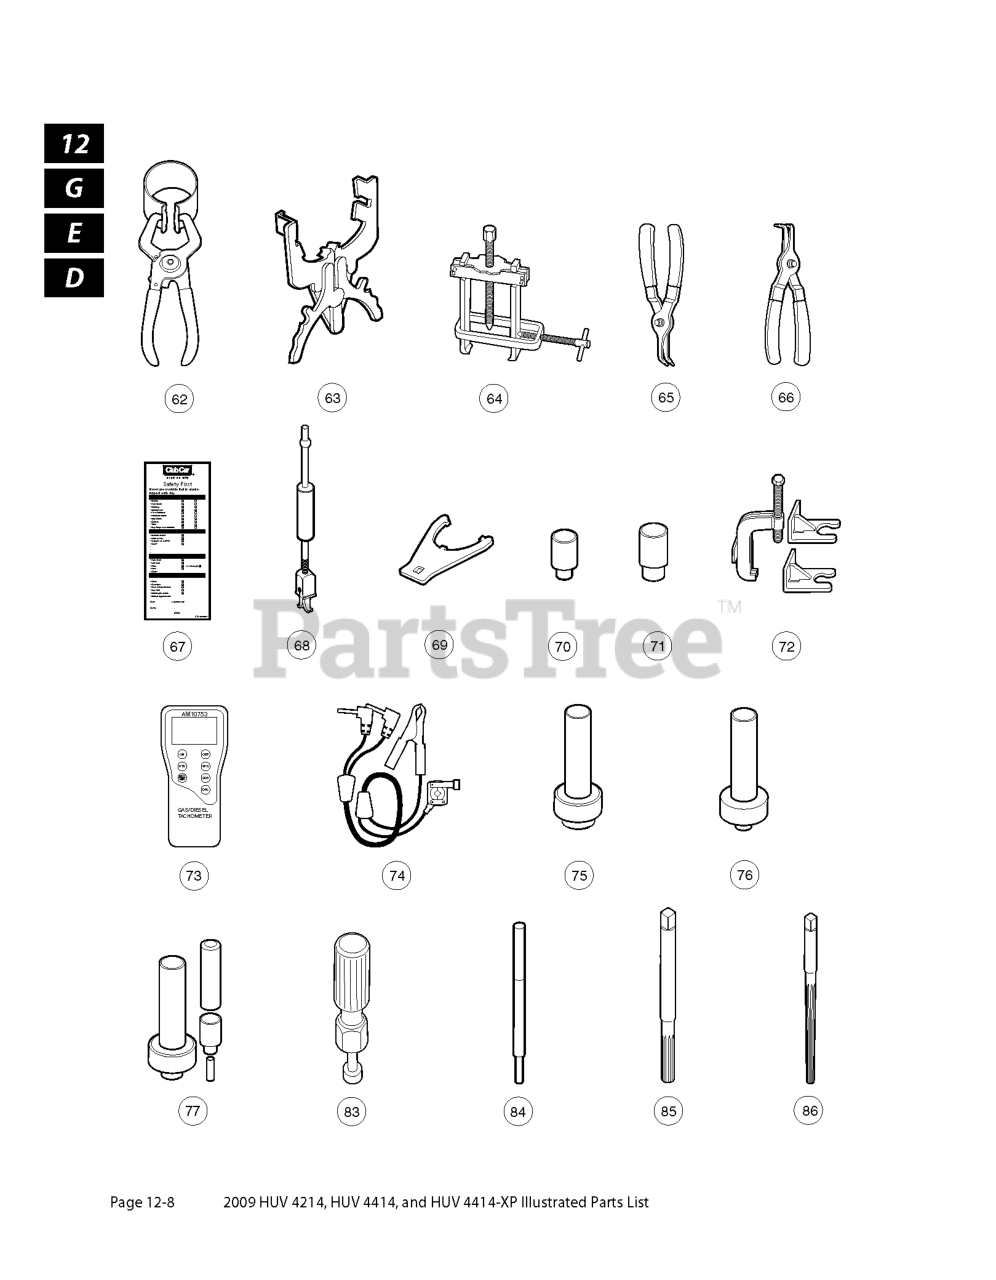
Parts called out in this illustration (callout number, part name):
62	KIT, PISTON RING COMPRESSOR
63	PISTON RING PLIER
65	EXTERNAL SNAP RING PLIERS
66	INTERNAL SNAP RING PLIER 9O
67	SAFETY FIRST CARD
68	SEAL PULLER
69	WRENCH, SPANNER
70	Steering Column Bearing Press Tool
71	TOOL-STEERING RETAINING RING
72	PULLER, STEERING WHEEL
73	TACHOMETER GAS/DIESEL
75	TRANS-AXLE, AXLE SEAL TOOL
76	Transaxle Pinion Seal Tool
77	Transmission Tool Kit
83	VALVE CLEAR ADJ SCREW HOLDER
84	DRIVER, VALVE GUIDE, 6.6. MM
85	VALVE GUIDE REAMER
86	REAMER-VALVE GUIDE
